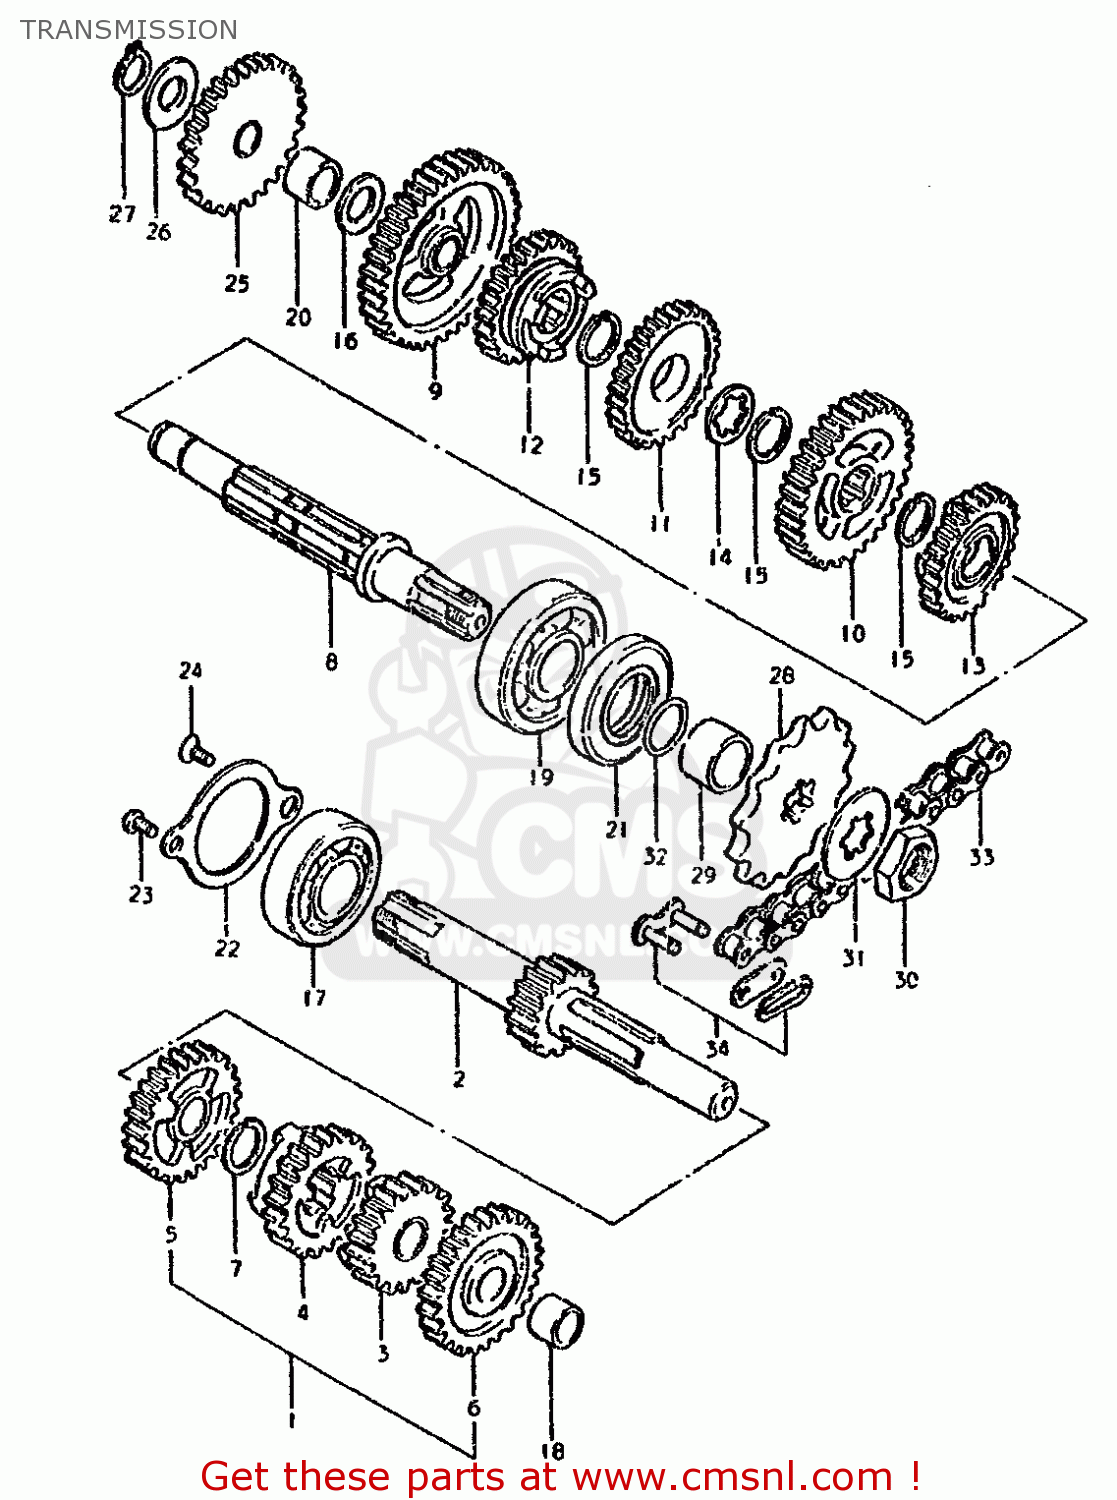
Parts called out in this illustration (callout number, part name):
1	SHAFT,COUNTER
2	SHAFT,COUNTER(NT:13)
3	GEAR,2ND DRIVE(NT:19)
4	GEAR,3RD DRIVE(NT:22)
5	GEAR,4TH DRIVE(NT:24)
6	GEAR,FIFTH DRIVE
7	CIRCLIP
8	SHAFT,DRIVE
9	GEAR,1ST DRIVEN(NT:35)
10	GEAR,2ND DRIVEN(NT:32)
11	GEAR,3RD DRIVEN(NT:29)
12	GEAR,4TH DRIVEN(NT:36)
13	GEAR,5TH DRIVEN(NT:24)
14	WASHER(13X24X1)
15	CIRCLIP
16	WASHER,LOCK
17	BEARING(17X40X12)
18	BUSH
19	BEARING
20	BUSH
21	SEAL,OIL(21X40X6)
22	RETAINER,CNTR SHAFT BEARING
23	SCREW
24	SCREW
25	GEAR,KICK STARTER IDLE
26	WASHER
27	CIRCLIP,12 MM
28	SPROCKET,ENGINE
29	SPACER(17X21X13)
30	NUT
31	WASHER,LOCK
32	O RING(D:1,ID:16.8)
33	CHAIN,DRIVE
34	JOINT,CHAIN
